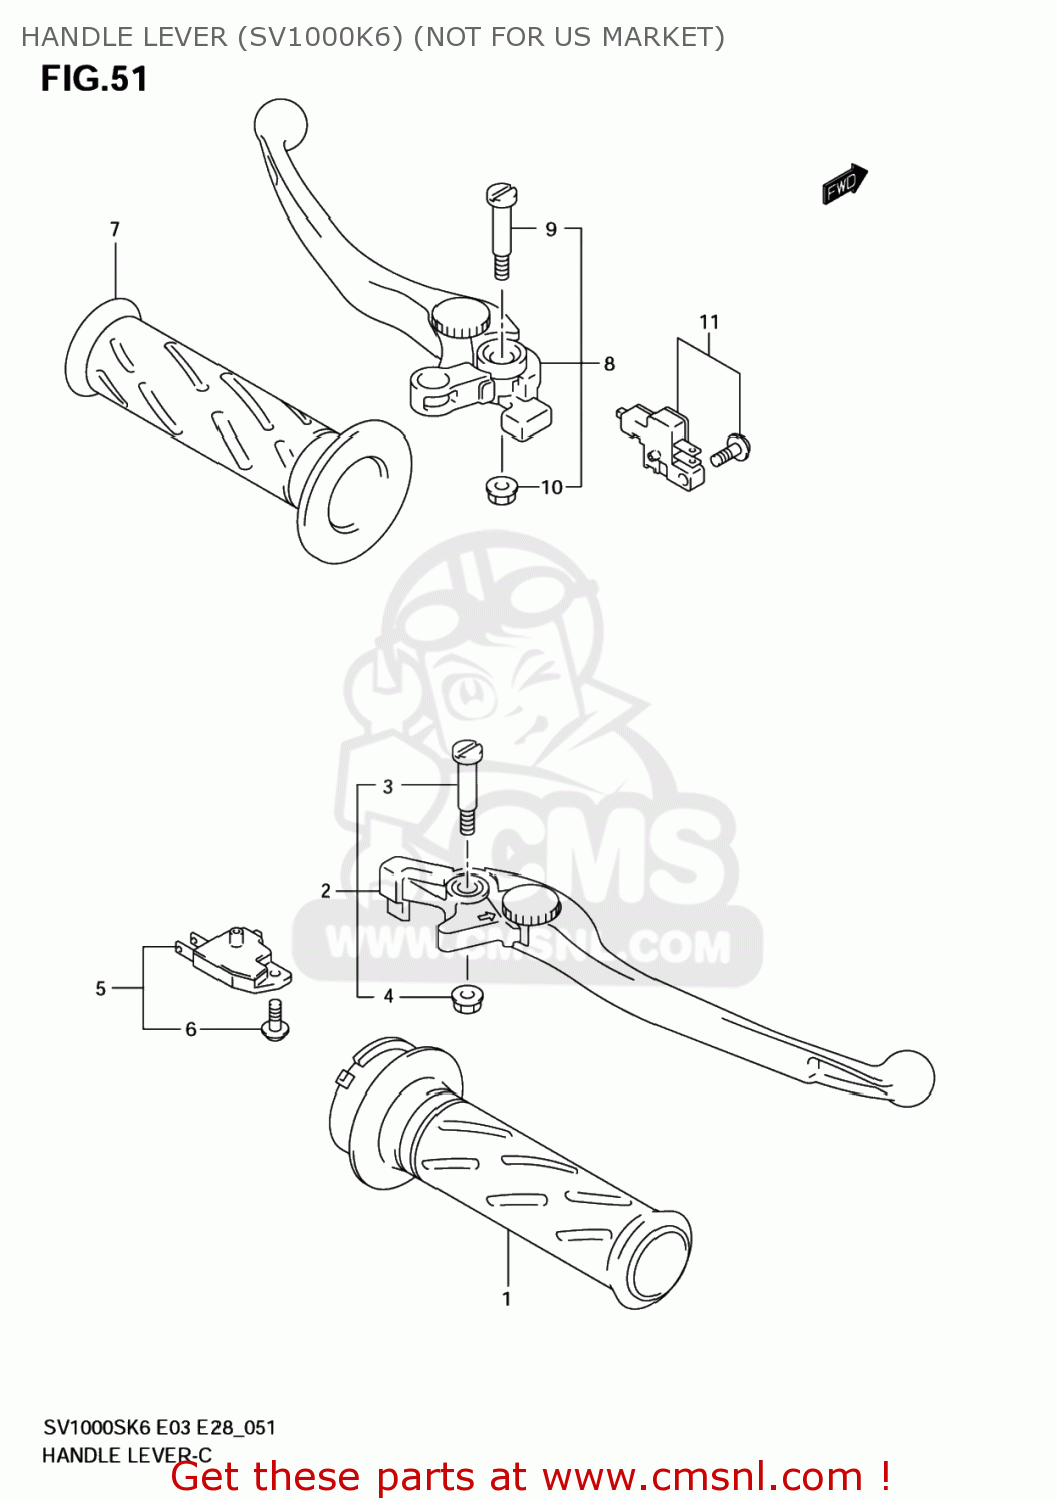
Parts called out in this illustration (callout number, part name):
1	GRIP,THROTTLE
2	LEVER ASSY,BRAKE
3	BOLT,LEVER PIVOT
4	NUT
5	SWITCH ASSY,ST
6	SCREW
7	GRIP,LEFT
8	LEVER ASSEMBLY,CLUTCH
9	BOLT,LEVER PIVOT
10	NUT
11	SWITCH ASSY,CLUTCH
